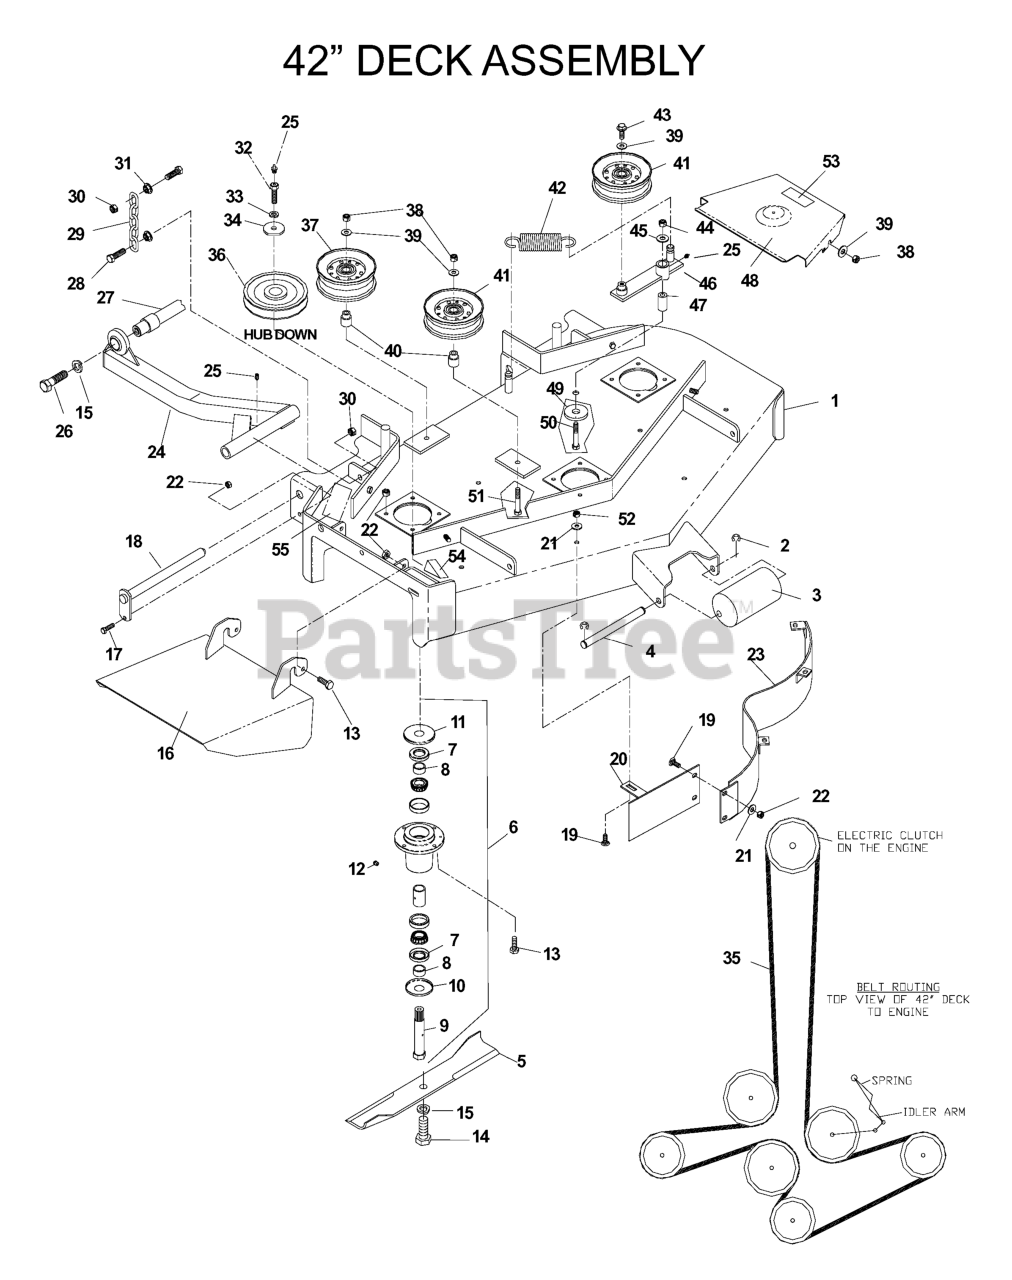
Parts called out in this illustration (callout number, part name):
1	DECK W/DECALS 42"
2	E-RING 1/2 (2 2)
5	BLADE OEM, 14-7/8
6	SPINDLE ASSY - 42/48"
7	SHAFT SEAL
9	SPLINED SHAFT - 42/48"
10	BOTTOM DUST CAP
11	TOP DUST CAP
12	PLUG-VENTED
13	HCS 5/16C X 1 1/4
14	HCS 5/8F X 1 1/4
15	LOCKWASHER 5/8
16	DISCHARGE CHUTE 42"
17	HCS 5/16C X 3/4
19	CARRIAGE BOLT 5/16C X 5/8"
20	CENTER BAFFLE
21	WASHER 5/16 FLAT
22	NUT 5/16 NYLOC
23	MAIN BAFFLE
24	STRUT WLDMT - RT
25	ZERK
26	HCS 5/8C X 2 GR.5
27	STRUT MOUNT WELDMENT
28	HCS 7/16C X 1 1/2
29	LIFT CHAIN
30	NUT 7/16C CENTERLOCK
31	NUT 7/16C WHIZ
32	DRILLED BOLT 7/16-20 X 1 1/2"
33	WASHER 7/16 LOCK
34	SPINDLE WASHER
35	BELT, DECK 42"
36	RP PULLEY - 42/48"
37	IDLER PULLEY (TALL)
38	NUT 3/8-16 NYLOC
39	WASHER 3/8 FLAT
40	IDLER BUSHING
41	IDLER PULLEY
43	4CS 3/8C X 1 SERRATED HEAD
44	NUT 1/2-13 HEX NYLOC ZD
45	WASHER 1/2 FLAT
47	PIVOT BUSHING
48	LT 42 SHIELD
49	WASHER, SUPPORT
50	HCS 1/2C X 3 1/4
51	SCREW 3/8C X 2 3/4 HEX CAP
52	NUT 5/16C CENTERLOCK
53	DECAL, NO STEP
54	DECAL, CPSC
55	DECAL, DANGER
539104621	STRUT SLDMT-LT
539108896	BELT SHIELD - RH
